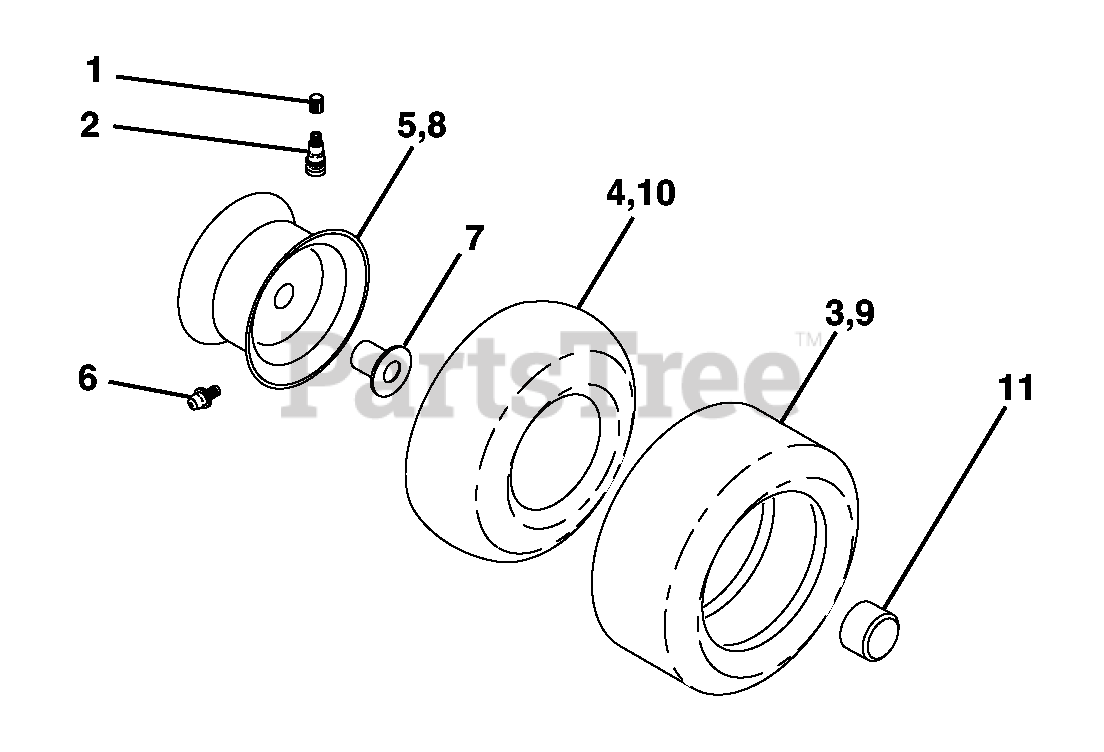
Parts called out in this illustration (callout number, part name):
1	Cap, Tire valve
2	Stem, Valve
3	Tire, Front
4	Tube, Front (Service item only)
5	Rim assembly, 6"front
6	Fitting, Grease (Front wheel only)
7	Bearing, Flange (Front wheel only)
8	Rim assembly, 8" rear
9	Tire, Rear
10	Tube, Rear (Service item only)
11	Cap, Hub Axle
